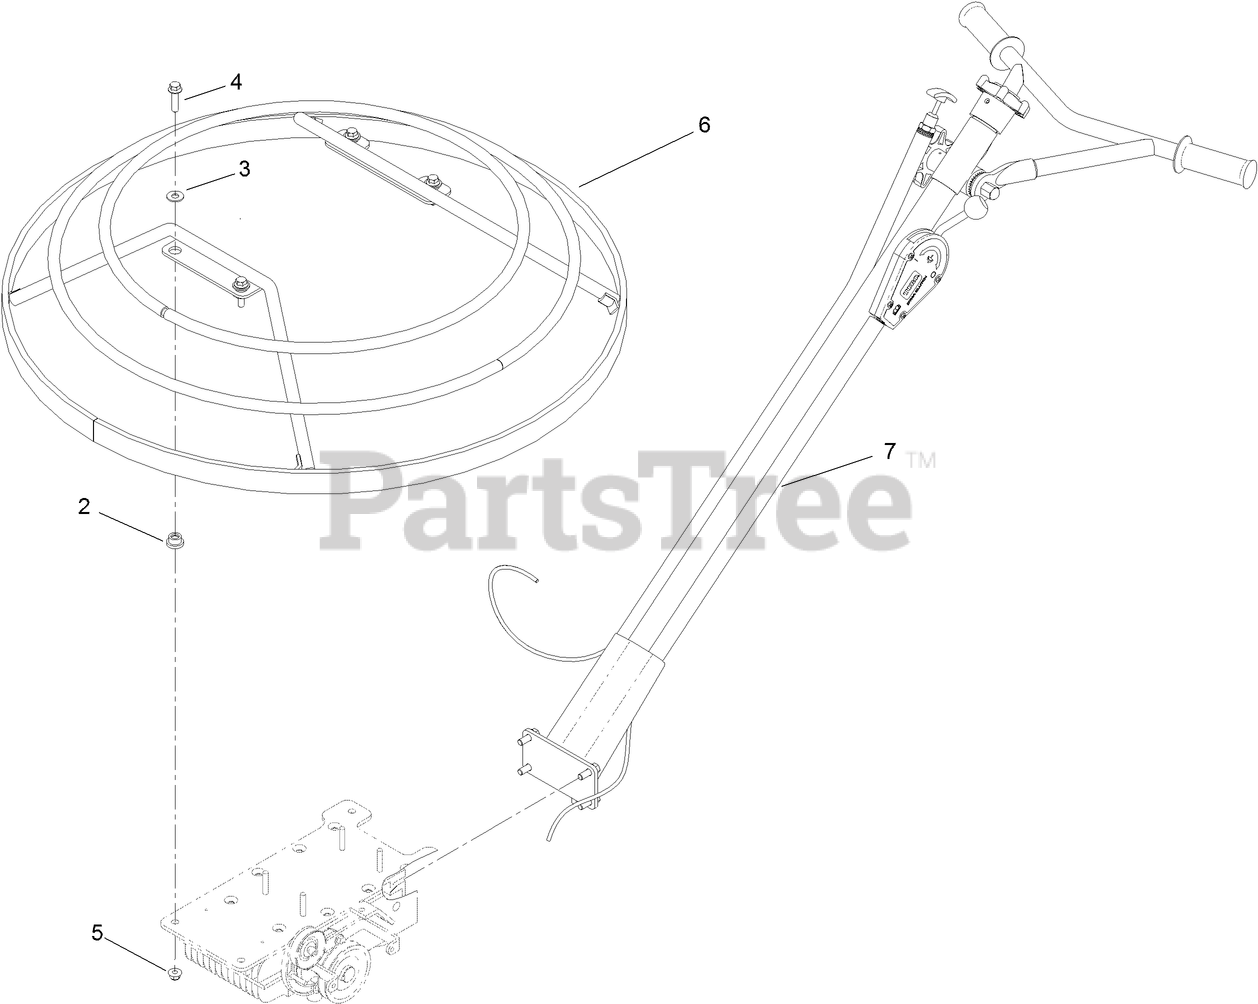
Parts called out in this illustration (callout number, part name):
2	MOUNT-SHOCK
3	WASHER-FLAT
4	SCREW-HHF
5	NUT-HF, NI
6	GUARD-STATIONARY
7	HANDLE-STANDARD
